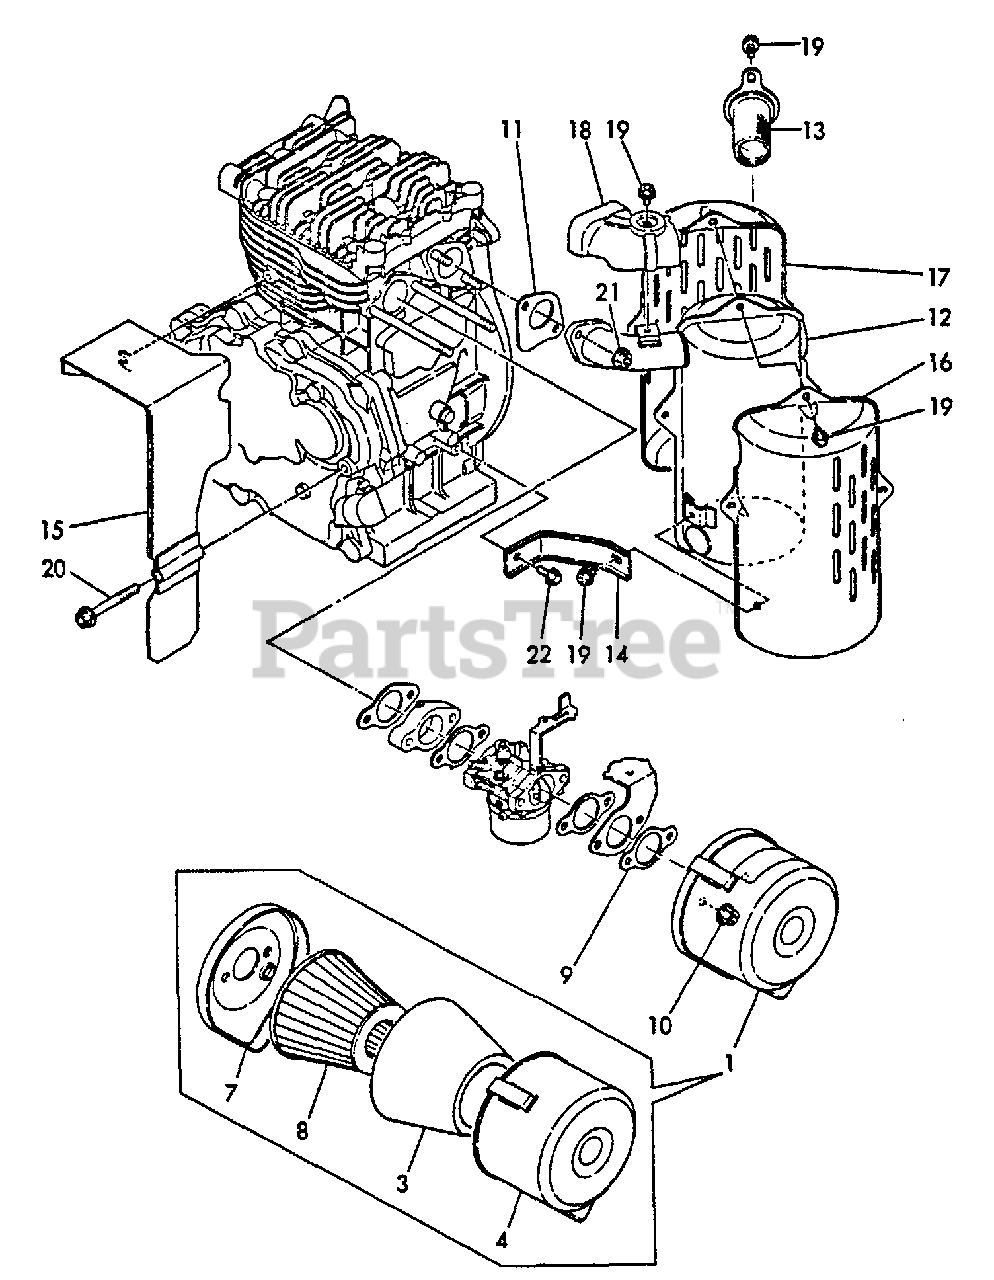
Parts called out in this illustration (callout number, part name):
1	AIR FILTER ASSY
3	FILTER, AIR
4	BODY ASSY
7	PLATE, PREVENT
8	ELEMENT
9	GASKET, INTAKE
10	U-NUT M8
11	GASKET, EXHAUST
12	SILENCER
13	SCREEN, SPARK ARRESTER
14	STAY, MUFFLER
15	PLATE, GUIDE
16	COVER-A, MUFFLER
17	COVER-B, MUFFLER
18	COVER-C, MUFFLER
19	BOLT - 6×8 -- PLATED
20	BOLT - 8×60 -- PLATED
21	U-NUT M8
22	BOLT - 6×8 -- PLATED
